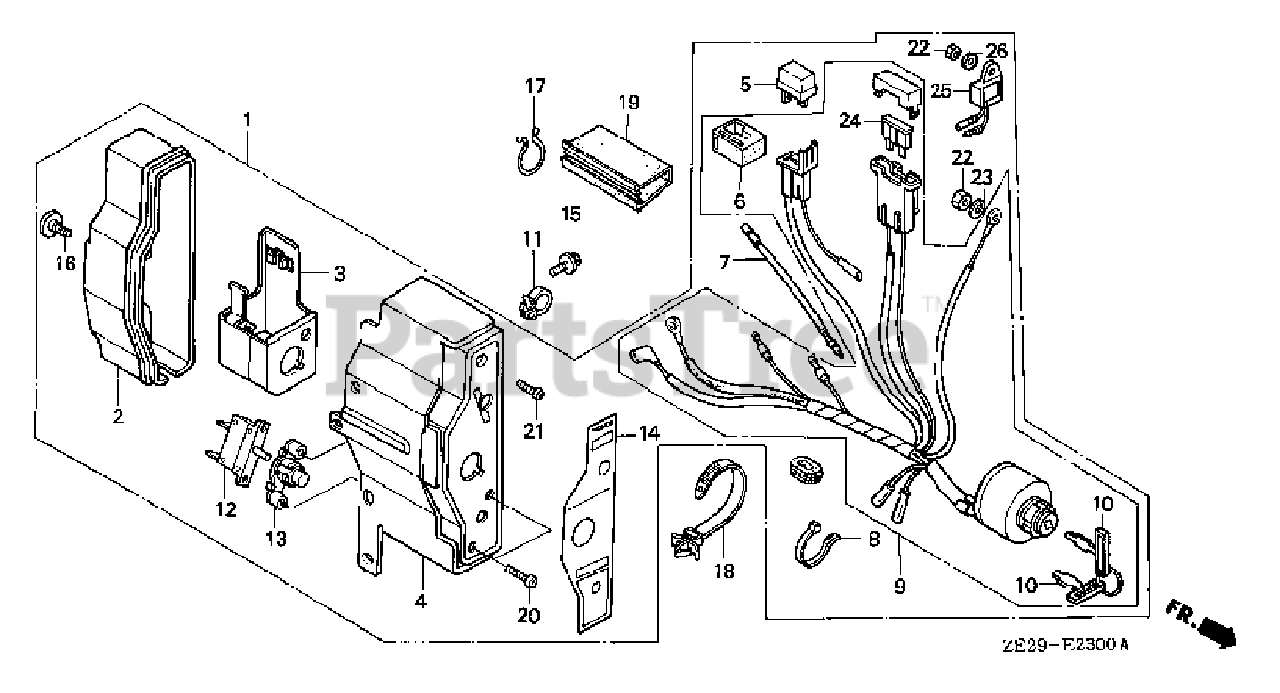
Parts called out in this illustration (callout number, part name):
1	BOX ASSY., CONTROL *NH1* (BLACK)
1	BOX ASSY., CONTROL (EXP-ALERT,3A) *R8* (BRIGHT RED)
2	CASE, CONTROL
3	BRACKET, CASE MOUNTING
4	PANEL, CONTROL *NH1* (BLACK)
4	PANEL, CONTROL *R8**R8* (BRIGHT RED)
5	RECTIFIER ASSY., SILICON (STANLEY)
6	SUSPENSION, CONNECTOR
7	SUB-HARNESS
8	BAND
9	SWITCH ASSY., COMBINATION
10	KEY
11	HOLDER, STOP SWITCH WIRE
12	PROTECTOR, CIRCUIT (3.5A)
13	LENS ASSY., PROTECTOR
14	PANEL, CONTROL BOX (EXTERNAL)
15	BOLT, FLANGE (6X12) (CT200)
16	SCREW, SPECIAL (6X12)
17	CLIP, PURSE LOCK
18	STRAP, CABLE (118MM) *NH1L* (BLACK)
19	TUBE, FASTENER (30)
20	SCREW, PAN (3X12)
21	SCREW, PAN (4X12)
22	NUT, HEX. (4MM) (NOT AVAILABLE)
23	WASHER, SPRING (4MM)
24	FUSE, BLADE (15A)
25	ALERT UNIT, OIL
26	WASHER, PLAIN (4MM)
